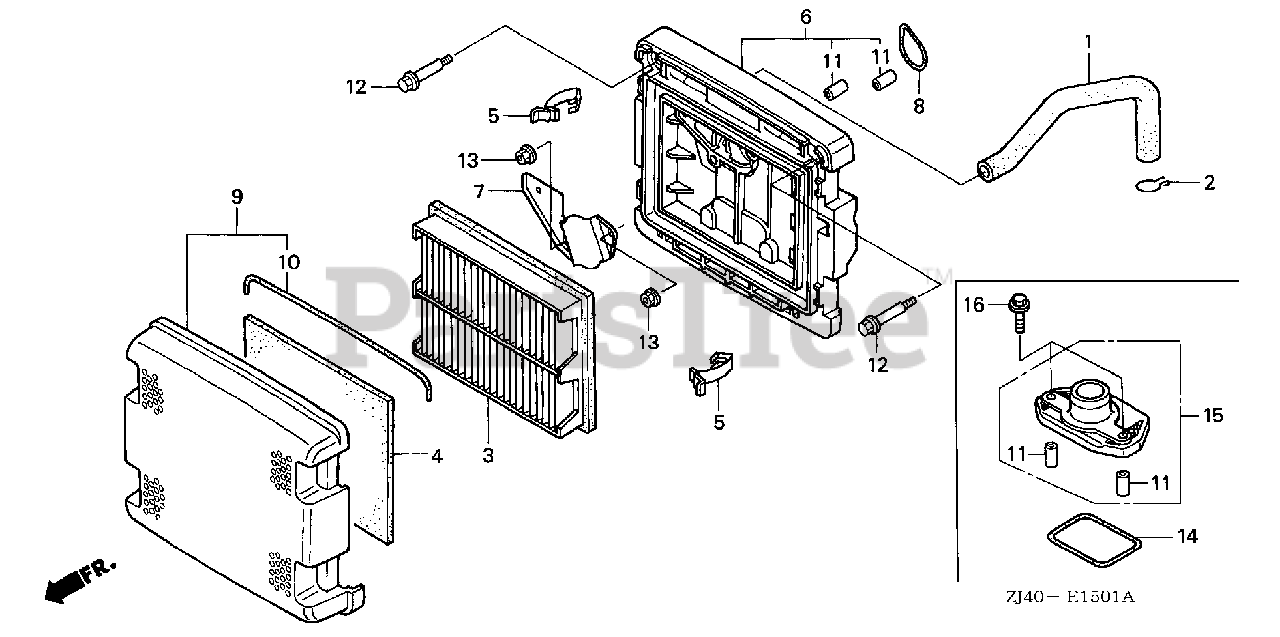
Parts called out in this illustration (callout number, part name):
1	TUBE, BREATHER
2	CLIP, BREATHER TUBE
3	ELEMENT, AIR CLEANER
4	FILTER (OUTER)
5	CLIP, AIR CLEANER
6	HOUSING, AIR CLEANER
7	CAP, AIR CLEANER
8	GASKET, AIR CLEANER
9	COVER ASSY., AIR CLEANER
10	SEAL, AIR CLEANER COVER
11	COLLAR A, AIR CLEANER
12	BOLT, SPECIAL (5MM)
13	NUT, FLANGE (6MM)
